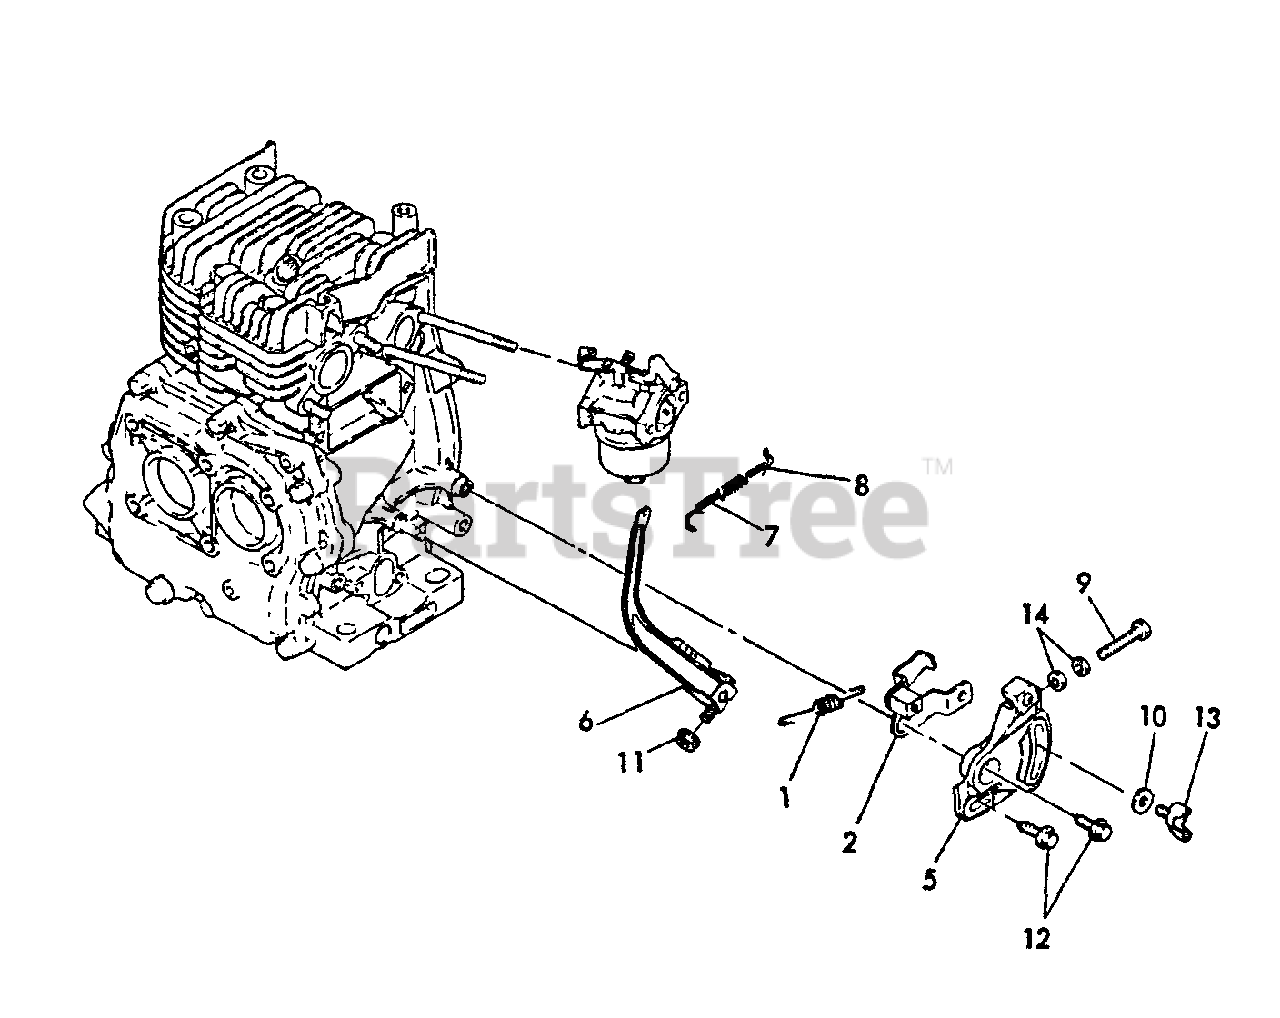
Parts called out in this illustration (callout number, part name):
1	SPRING, REGULATOR
2	REGULATOR HANDLE ASSY
5	BRACKET, REGULATOR
6	LEVER, GOVERNOR
7	LINK, THROTTLE
8	SPRING
9	BOLT
10	WASHER - 6
11	NUT - 6 -- FLANGE
12	BOLT - 6X20
13	THUMBSCREW
14	LOCKNUT - 6 -- PLATED
